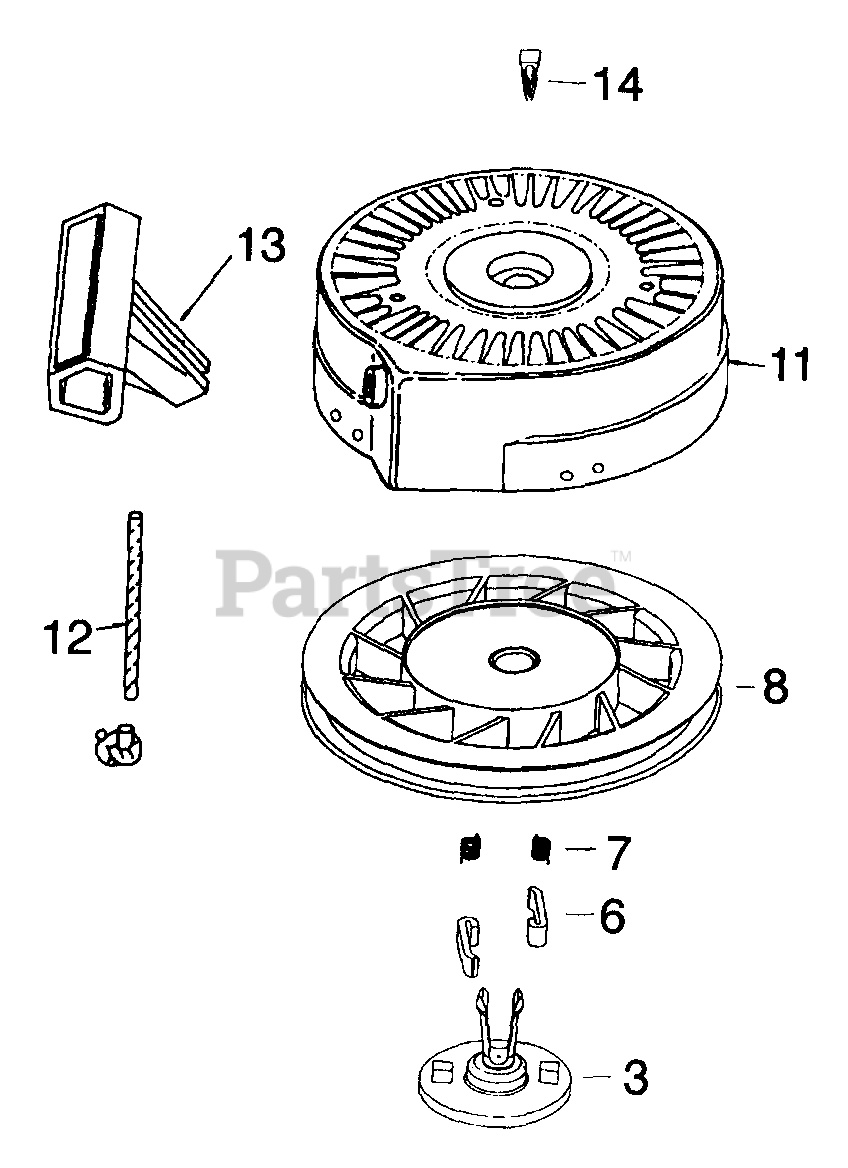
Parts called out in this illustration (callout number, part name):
6	Starter Dog
7	Dog Spring
8	Pulley & Rewind Spring Assy
11	Starter Housing Assy
12	Starter Rope
13	Starter Handle
14	Locking Tab
